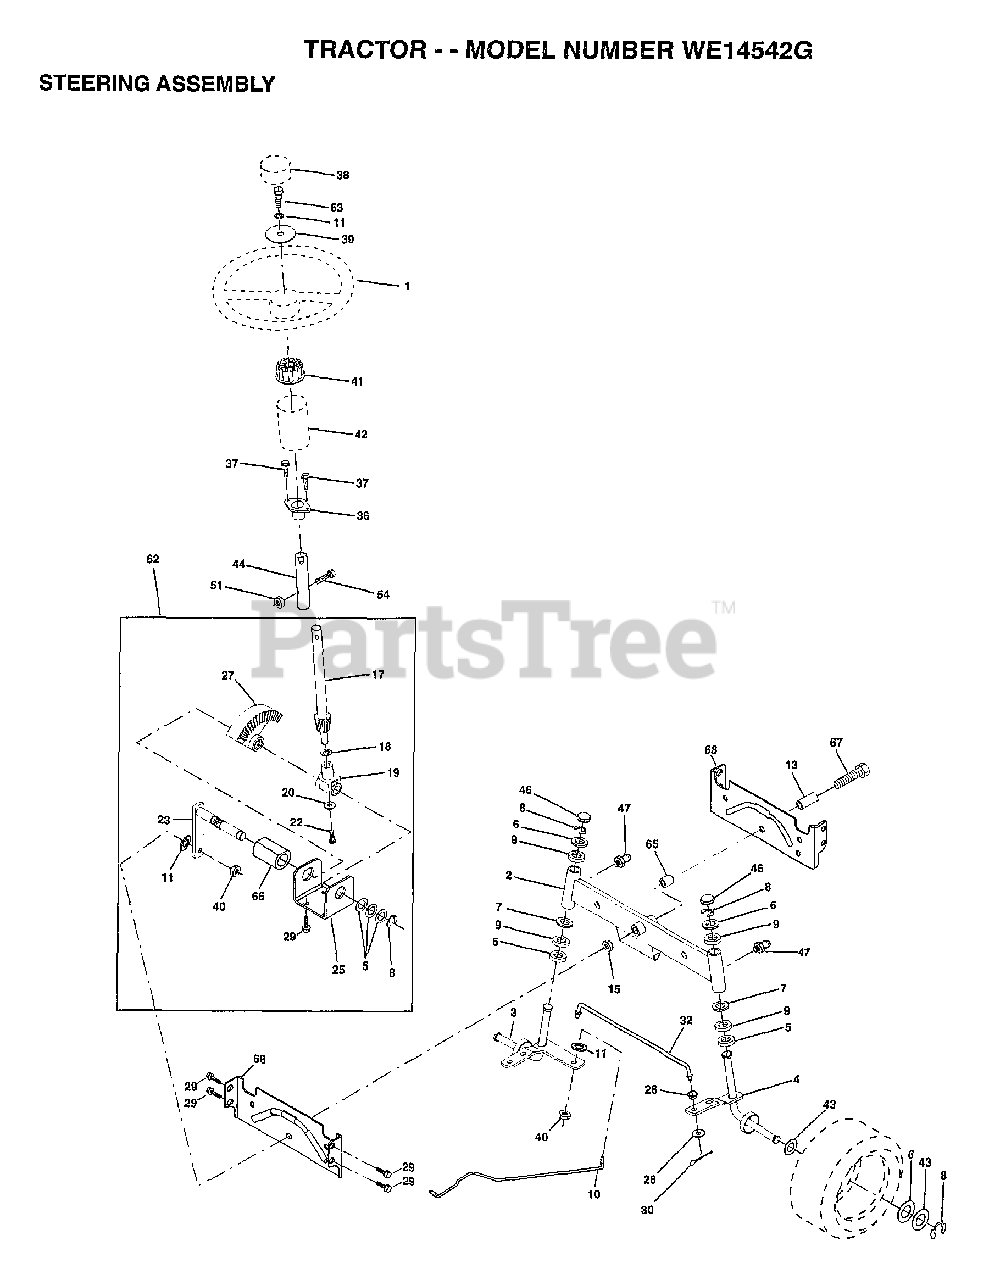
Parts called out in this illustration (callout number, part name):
1	WHEEL STR AYP BLK
2	AXLE ASM
3	SPINDLE.ASM.LH
4	"SPINDLE ASM,RH"
5	WASHER .T
6	WASHER
7	WASHER
8	RING
9	COL. SRTG. BEAR.
10	DRAGLINK-STAMPED
11	LOCKWASHER
13	BEARING AXLE
15	"NUT-LOC,FLANGE LT"
17	SHAFT ASM STEERIN
18	THRUST WASHER
19	SUPPORT.SHAFT
22	SCREW HEX SOC1/4-
25	BRKT-STEERING
26	BUSHING.DRAGLINK
27	GEAR SECTOR
28	WASHER
29	SCREW
30	COTTER PIN
32	TIE ROD
36	BUSHING.STEERING
37	"SCREW-TT,10-32 FL"
38	CAP STEER AYP
39	WASHER T
40	GRIPCO NUT
41	ADAPTER LT
42	BOOT.STEER.PL
43	WASHER
44	EXT SHAFT STEERIN
46	CAP
47	ZERK M
51	NUT
54	BOLT
62	KIT STEERING ASM
63	BOLT
65	SPACER AXLE
66	"BEARING-ARM,PITMA"
67	BOLT
68	BRACE AXLE
